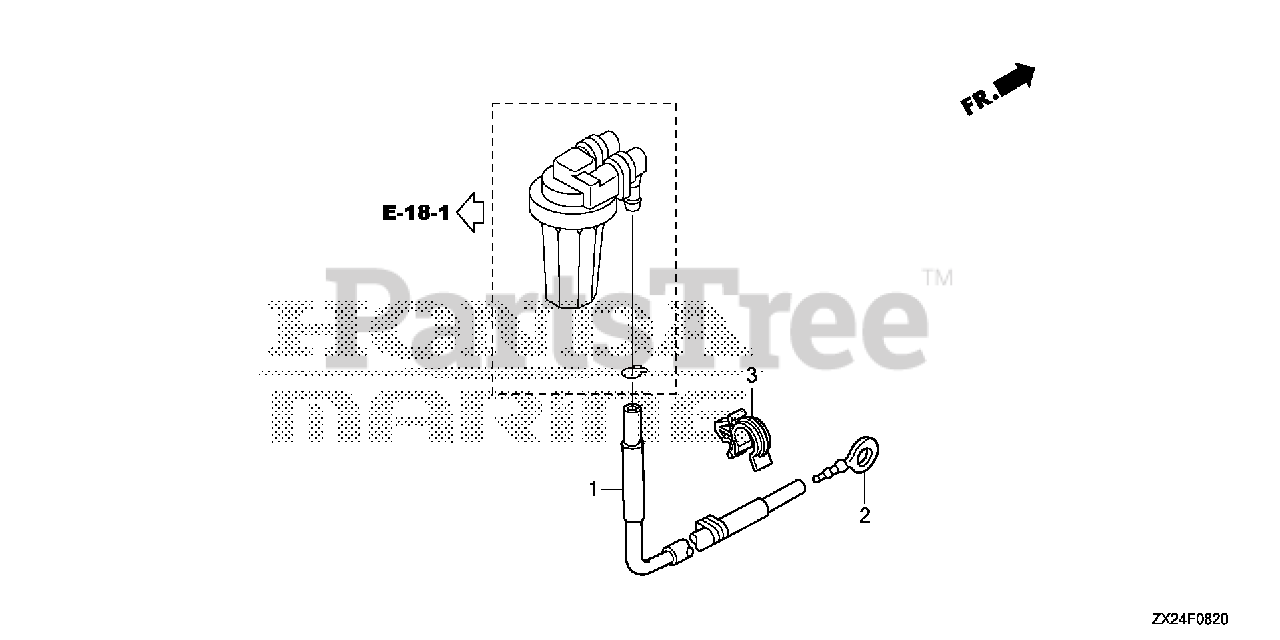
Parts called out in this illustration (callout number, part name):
1	TUBE A, FUEL
2	PLUG, FUEL TUBE
3	HOLDER, ROD (A)
